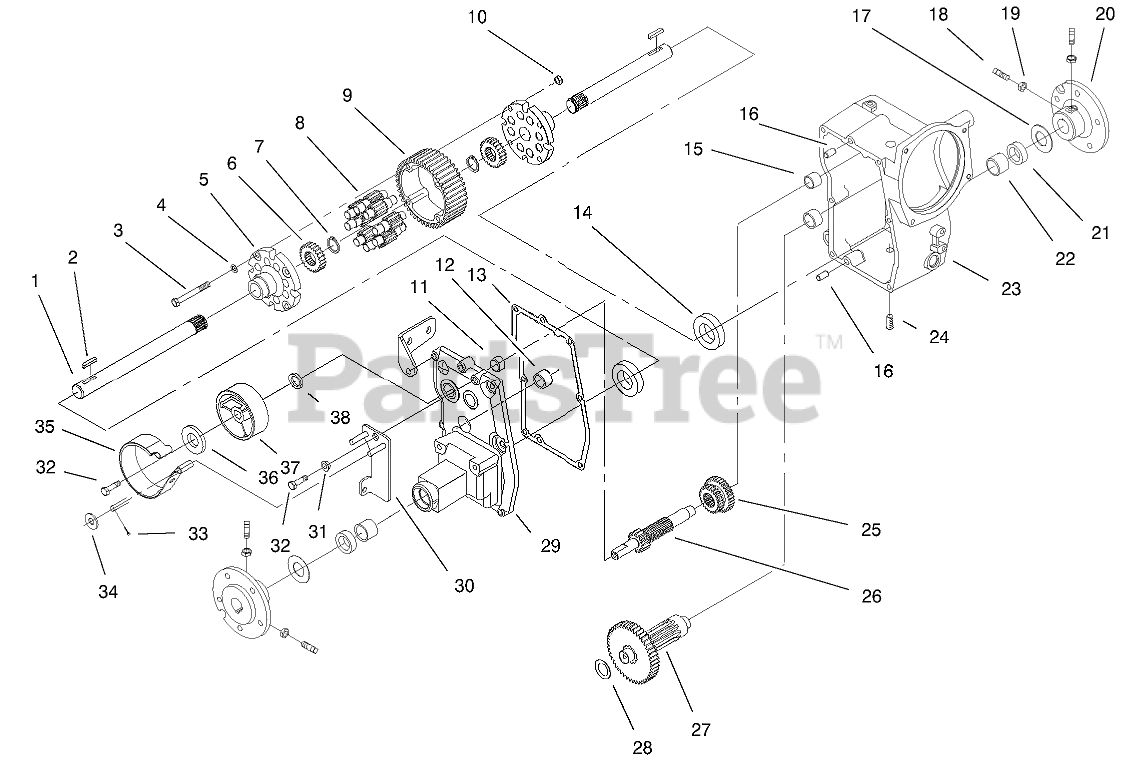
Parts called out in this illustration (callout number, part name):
1	AXLE-REAR
3	BOLT-HEX
4	WASHER
5	END CAP-DIFFERENTIAL
6	GEAR-AXLE DIFFERENTIAL
7	RING-SNAP
8	GEAR-PINION, 11T
9	GEAR-DIFFERENTIAL RING, 43T
11	BEARING-NEEDLE
12	BEARING-NEEDLE
13	GASKET-CASE
14	BEARING-BALL
15	BEARING-NEEDLE
16	PIN-LOCATING
17	WASHER-THRUST
18	SCREW-SET, SQH
19	NUT-JAM
20	HUB-WHEEL
21	SEAL-OIL
22	BEARING
23	CASE-LH
24	PLUG-PIPE
25	GEAR-SLIDING
26	SHAFT-BRAKE
27	GEAR ASM
28	WASHER-THRUST
29	CASE-RH
30	Arm-PIVOT, Brake
31	CAM-SPACER
32	SCREW-HH, LOCK
33	PIN-COTTER
34	WASHER-FLAT
35	BAND-BRAKE
36	WASHER
37	DRUM-BRAKE
38	SEAL-OIL
